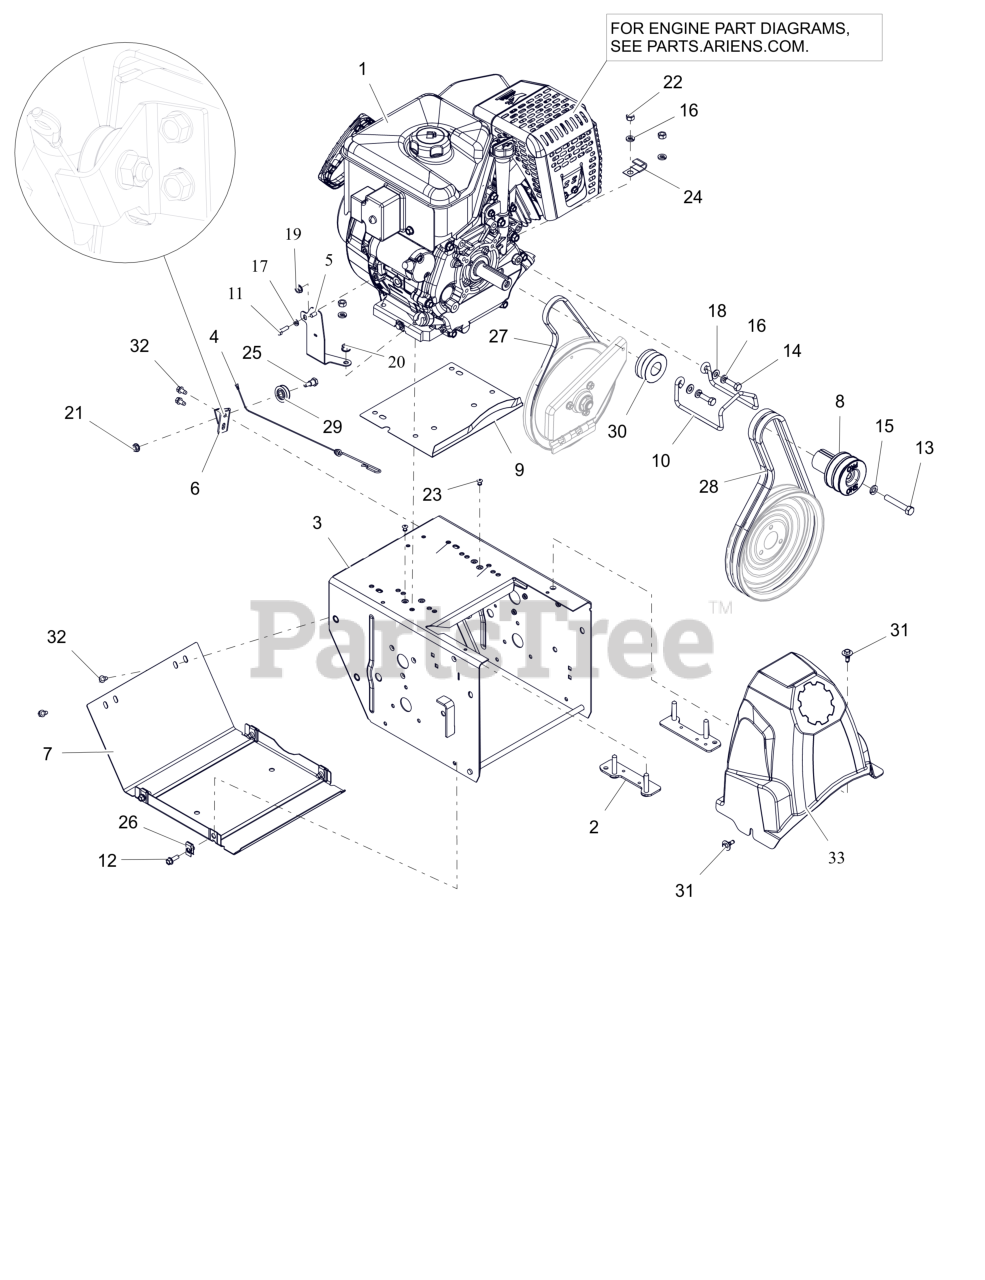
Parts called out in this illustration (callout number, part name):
1	ENGINE,EFI306 GEN3 120V/60W
2	STRAP, ENGINE-MEDIUM BLOCK
3	FRAME, MAIN - 14GA DELUXE (ORANGE)
4	CABLE, LOWER TRACTION,SS & PRO
5	WLDMT- MED BLOCK FUSE MOUNT
6	BRACKET, CABLE PULLEY
7	COVER, BOTTOM
8	SHEAVE,ATTACHMENT-SHO 2 GRV
9	BAFFLE, WATER - LARGE BLOCK
10	FINGER, BELT
11	BLT,HEX M6-1X20 G8.8 ZC120
12	BLT, HWH .25-20X.75 G5 ZCC
13	BLT, HEX .38-24X2.25 G5 ZCC
14	BLT, HEX 0.3125-24X1 G5 ZCC
15	WSHR,LK-REG .375X.094 ZCC
16	WSHR, LK-HVY .312X.097 ZCC
17	WSHR,LK-REG .250X.062 ZCC
18	WSHR,FLT .344X.688X.065 ZCC
19	NUT-LK-CTR-FLG .25-20 ZC120
20	NUT,LK-CTR-FLG .31-18 GF ZCC
21	NUT-LK-TOP-FLG .250-20 GF ZCC
22	NUT, HEX .312-18 ZCC
23	RVT, POP .1875 ZCC
24	J-CLAMP
25	BOLT, SHLDR -.375 X .375 X .25-20
26	NUT-RTNR .25-20X.56
27	V-BELT, 3L-WRAPPED
28	V-BELT, HA-RAW EDGE (SET)
29	PULLEY, CABLE
30	SHEAVE, TRACTION (KEYLESS)
31	SCR-TAP .25-20X.5 CAPTIVE
32	SCR-TAP .25-20X.50 HWH ZCC
33	COVER, BELT
